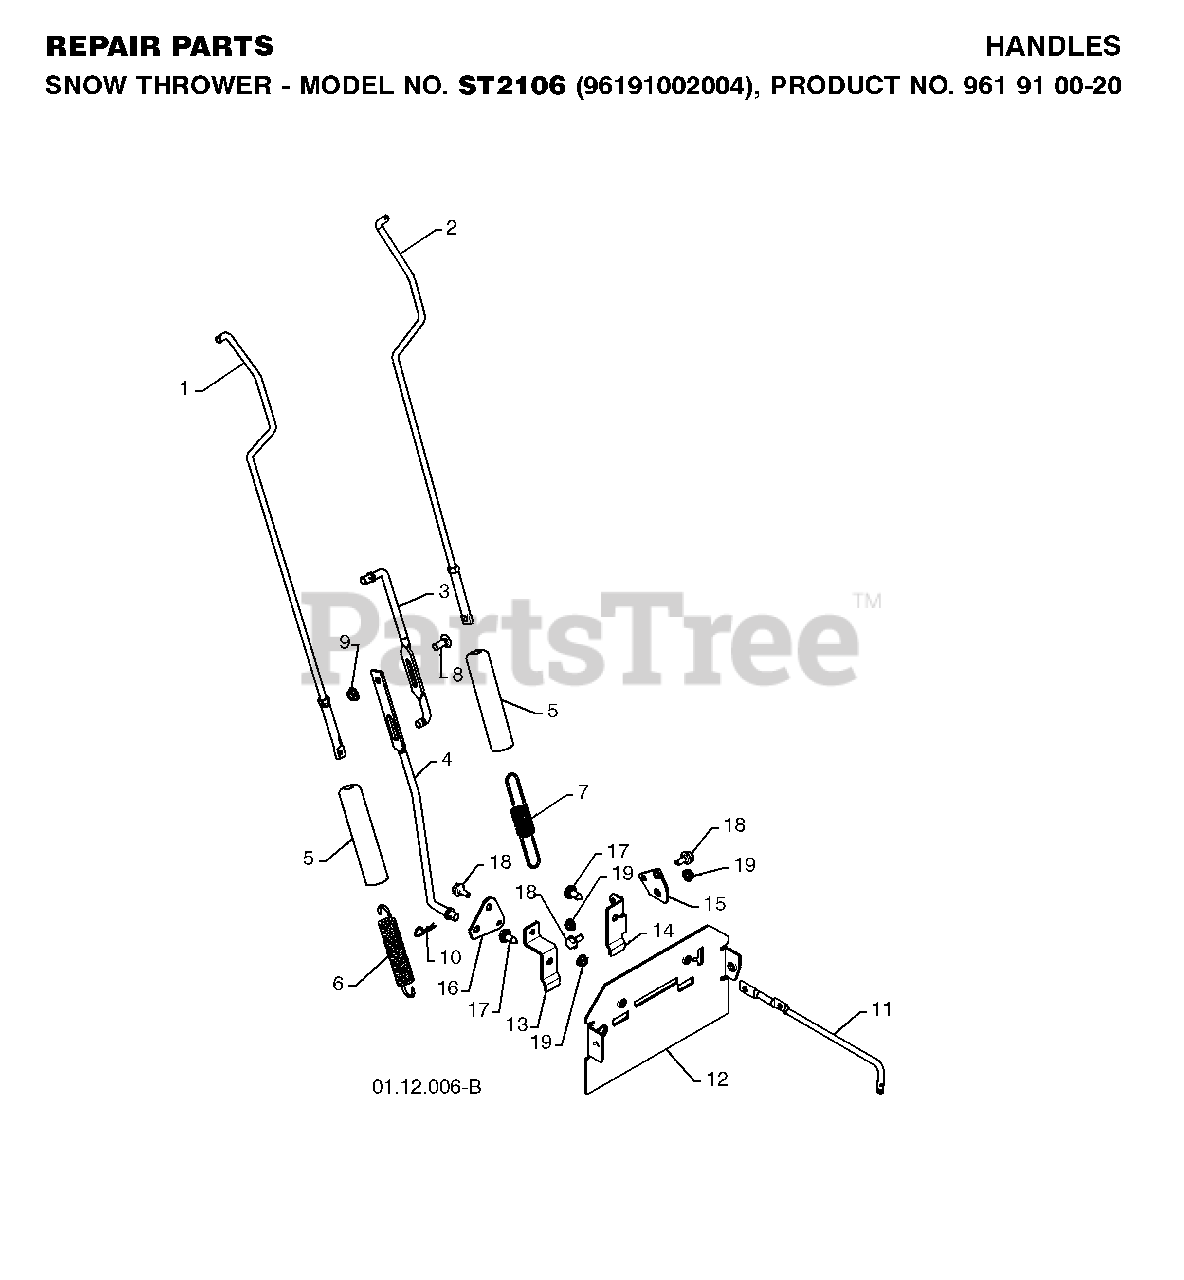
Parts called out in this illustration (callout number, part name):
1	ROD.ASM.IMPELLER
2	ROD.ASM.TRACTION
3	ROD, UPPER SPEED CONTROL
4	ROD, LOWER SPEED CONTROL
5	SLEEVE, SPRING
6	SPRING, AUGER CONTROL
7	SPRING, TRACTION DRIVE
9	NUT.FLANGE.5/16
10	SPRING RETAINER
11	ROD.CLUTCH.YELLOW.ZINC(VT)
13	BRACKET.SHIFTER.PLATE.BZP
14	BRACKET.CLUTCH.PLATE.BZP
15	PLATE.CLUTCH.BZP
16	PLATE.SHIFTER.BZP
18	BOLT.SHOULDER.3/X.25
19	NUT.HEX.FLANGE.1/4
